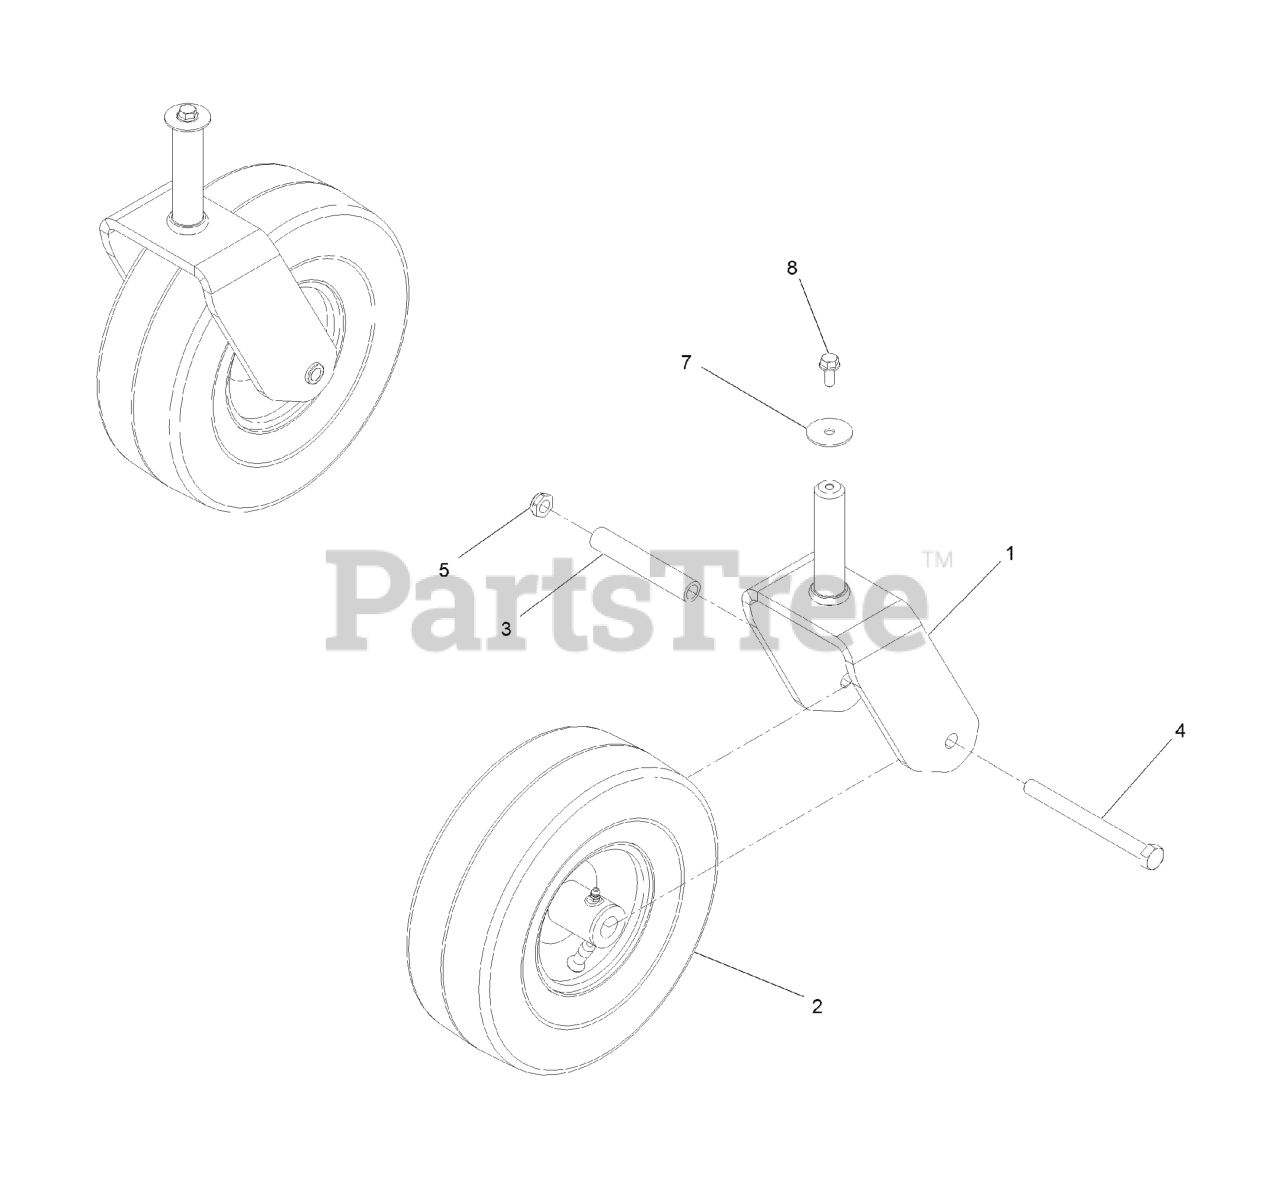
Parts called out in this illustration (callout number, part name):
1	FORK-CASTER
2	TIRE AND WHEEL ASM (C S T)
3	BUSHING-SPANNER
4	SCREW-HH
5	NUT-HEX
7	WASHER-FLAT
8	SCREW-HHF
